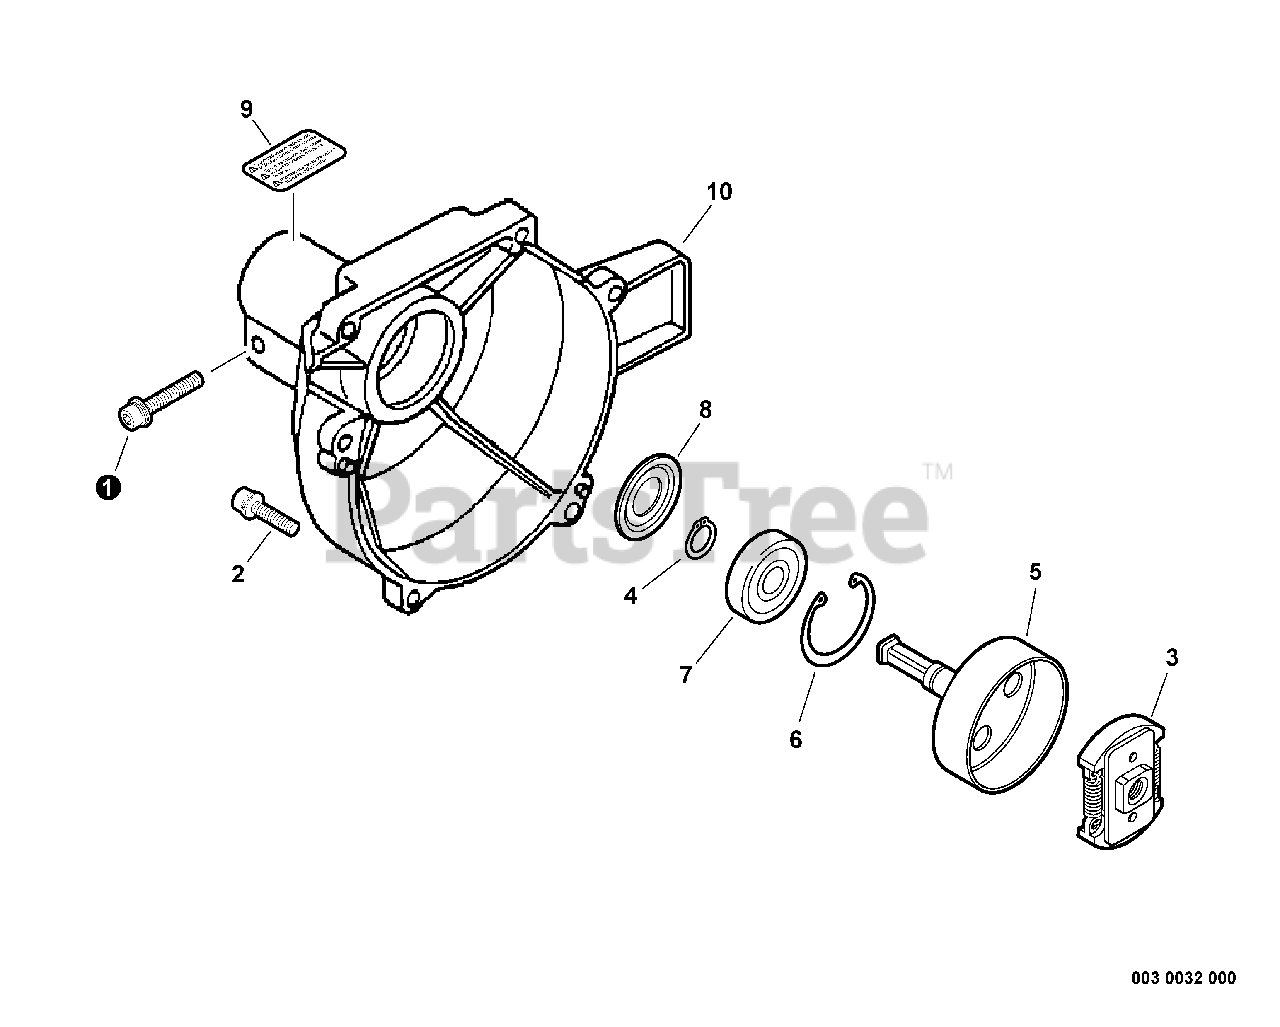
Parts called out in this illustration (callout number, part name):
1	BOLT 5×25
2	BOLT 4×16
3	CLUTCH ASSY
4	RING, RETAINING - 12
5	DRUM, CLUTCH
6	RING, SNAP Ø32
7	BEARING, BALL 6201
8	STOPPER, PIPE
9	LABEL, CAUTION
10	CASE, FAN
